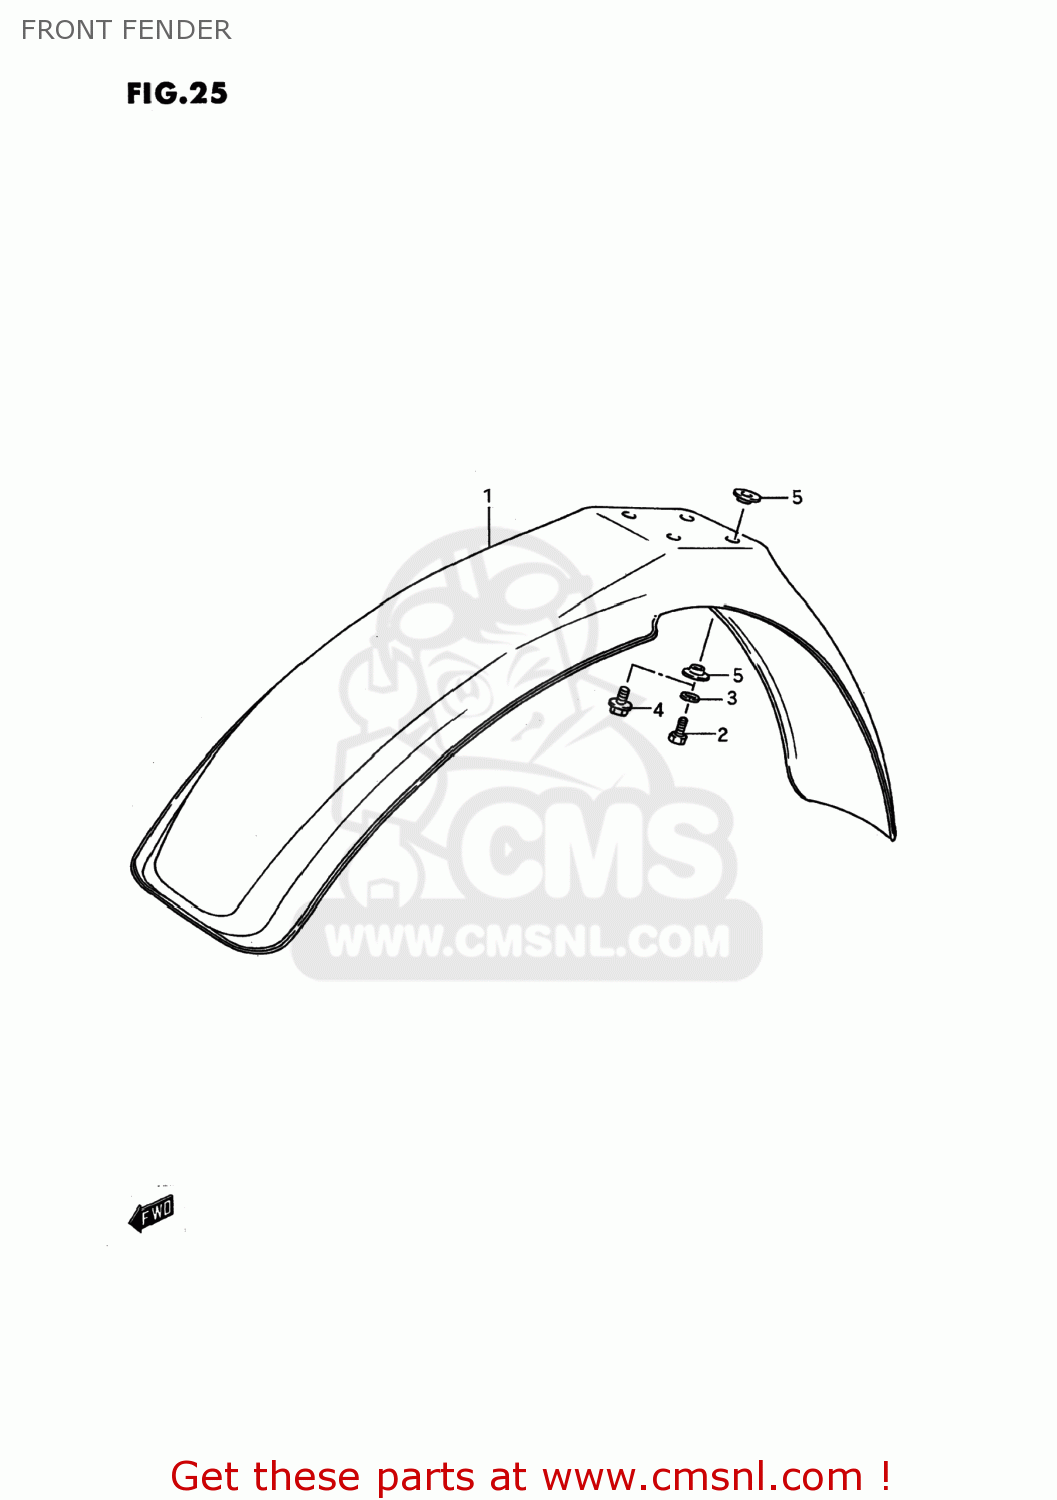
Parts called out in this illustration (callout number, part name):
1	FENDER,FRONT
2	BOLT
3	WASHER,LOCK
4	BOLT
5	WASHER
